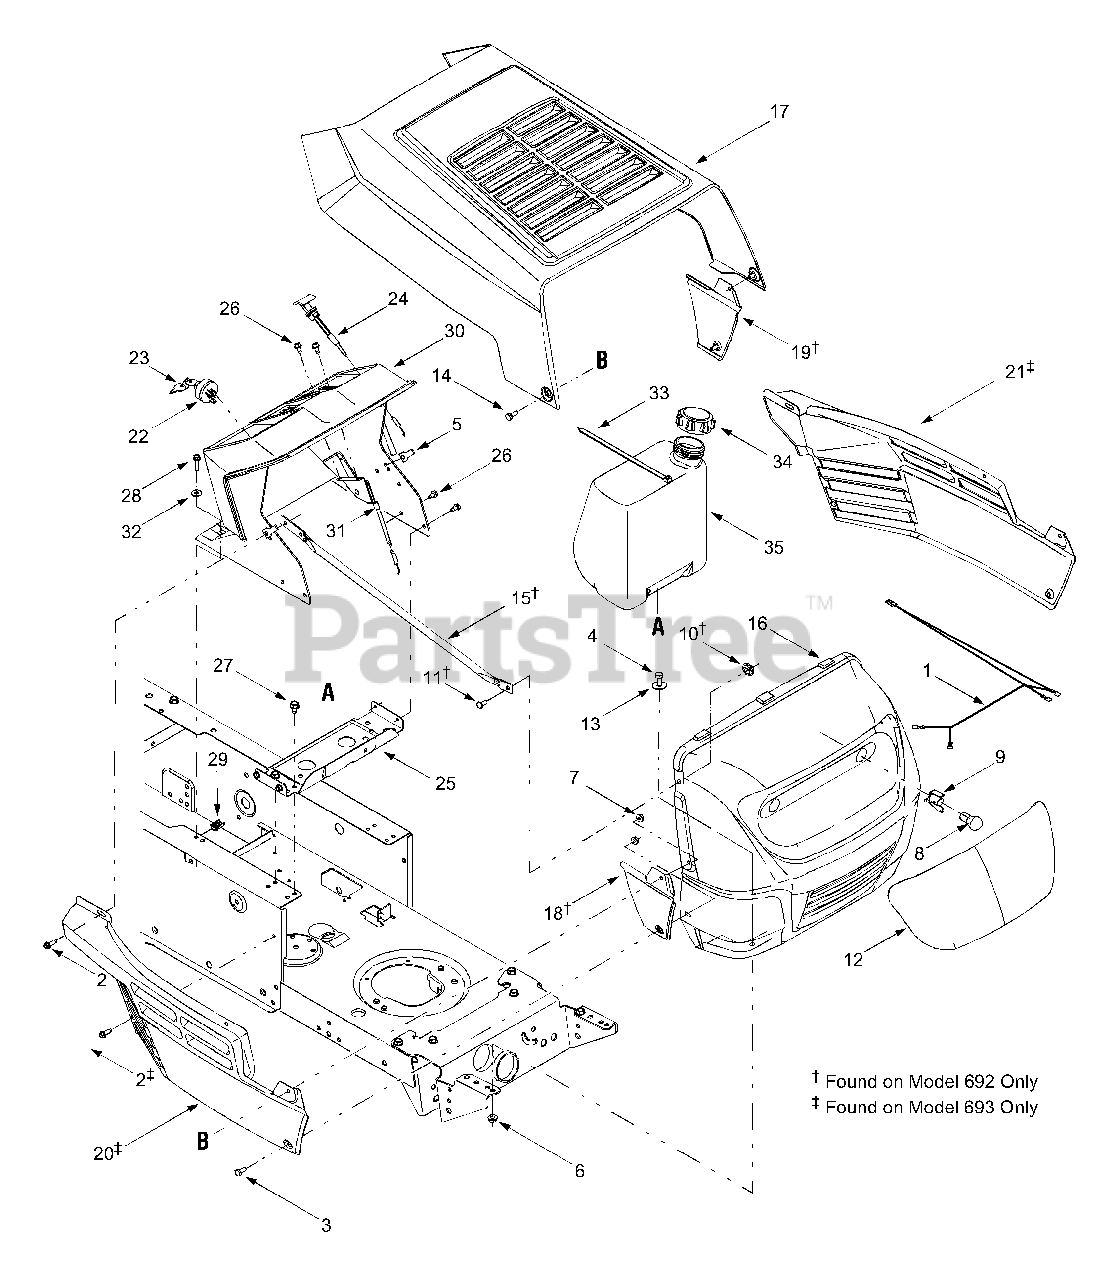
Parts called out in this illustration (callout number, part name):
1	Headlamp Harness Assembly
2	Self-tapping Screw, 1/4-20 x .75
3	Hex Screw, 1/4-20 x .620
4	Hex Screw, 5/16-18 x .75
5	U-type Speed Nut, 1/4-20
6	Flange Lock Nut, 5/16-18
7	Flange Lock Nut, 1/4-20
8	Headlamp, 12V
9	Headlamp Socket
10	Push-on Nut, .25
11	Flat-head Rivet, 1/4
12	Lens
13	Flat Washer, .344 x 1.0 x .063
14	Shoulder Screw, 1/4-20 x .375 /.125
23	Keys (pair)
24	Choke Control, 38"
24	Choke Control, 23"
25	Battery Support Bracket
26	Self-tapping Screw, 1/4-20 x .5
27	Self-tapping Screw, 5/16-18 x .5
28	Self-tapping Screw, 1/4-20 x 1.0
29	U-type Speed Nut, 1/4-20
30	Dash Panel (models w/o choke knob)
30	Dash Panel (models w/ choke knob)
31	Throttle / Choke Control, 18.5"
31	Throttle Control, 35.5"
31	Throttle Control, 18.5"
32	Flat Washer, .260 x .720 x .060
33	Cable Tie, 30.66
34	Fuel Tank Cap
35	Fuel Tank, 1.5 gal.
